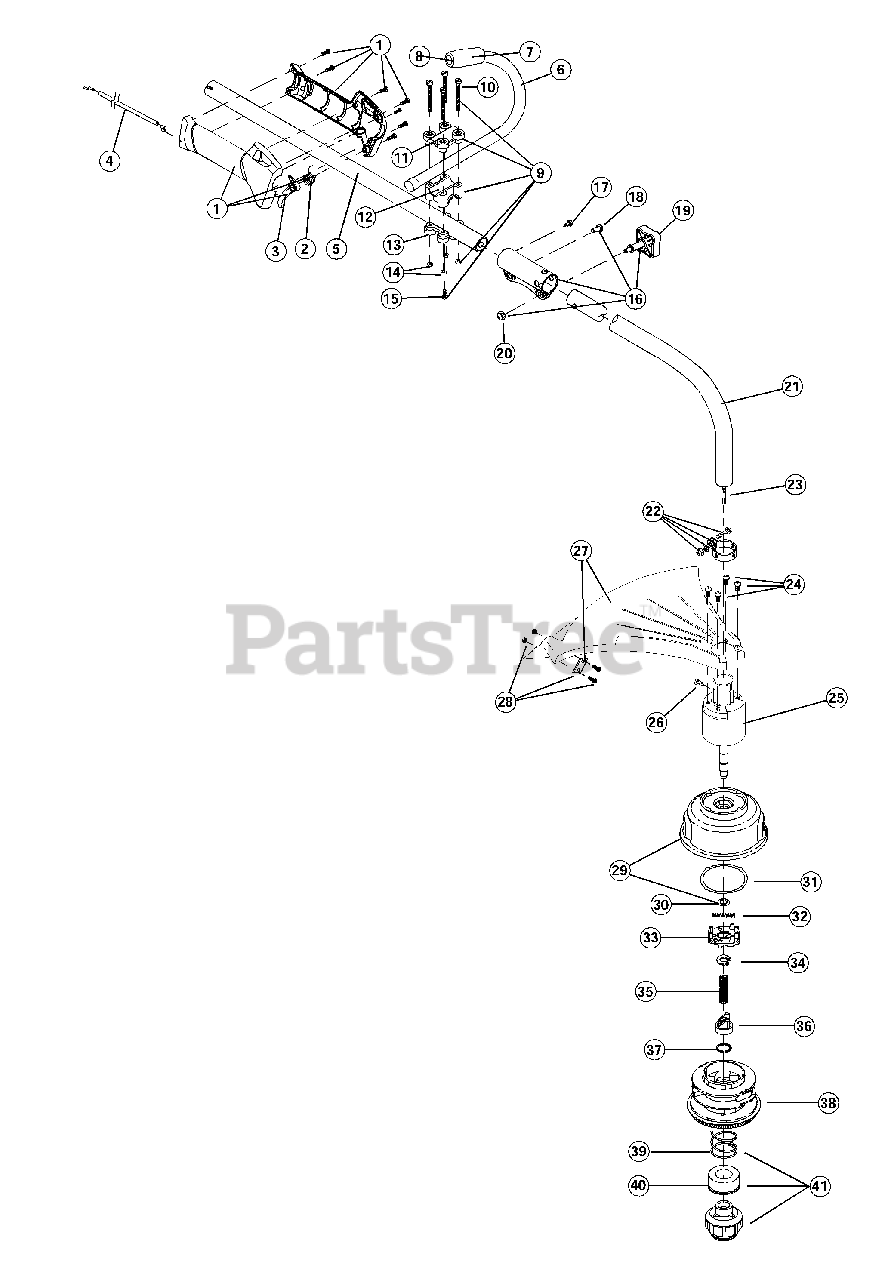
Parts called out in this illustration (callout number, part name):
1	Throttle Housing Assembly
2	Throttle Trigger Spring
3	Throttle Trigger
4	Throttle Cable Assembly
5	Upper Drive Shaft Housing Assembly
6	J-Handle Assembly
8	Tube Closure
9	Handle Bracket Assembly
11	Upper Handle Clamp
12	Middle Handle Clamp
13	Lower Handle Clamp
15	Anti-Rotation Screw
16	Click-Link Coupler
19	Adjustment Knob
20	Knob Retaining Nut
21	Lower Drive Shaft Housing Assembly
22	Lower Clamp Assembly
23	Lower Flexible Drive Shaft
24	Shield Mounting Screw
25	Bushing Housing Assembly
26	Anti-Rotation Screw
27	Shield and Blade Assembly
28	Blade Assembly
29	Outer Spool Assembly
30	Retainer
31	Thrust Washer
32	Small Spring
33	Slider
36	Plunger
38	Inner Reel
39	Large Spring
40	Foam Seal
41	Bump Head Knob Assembly
